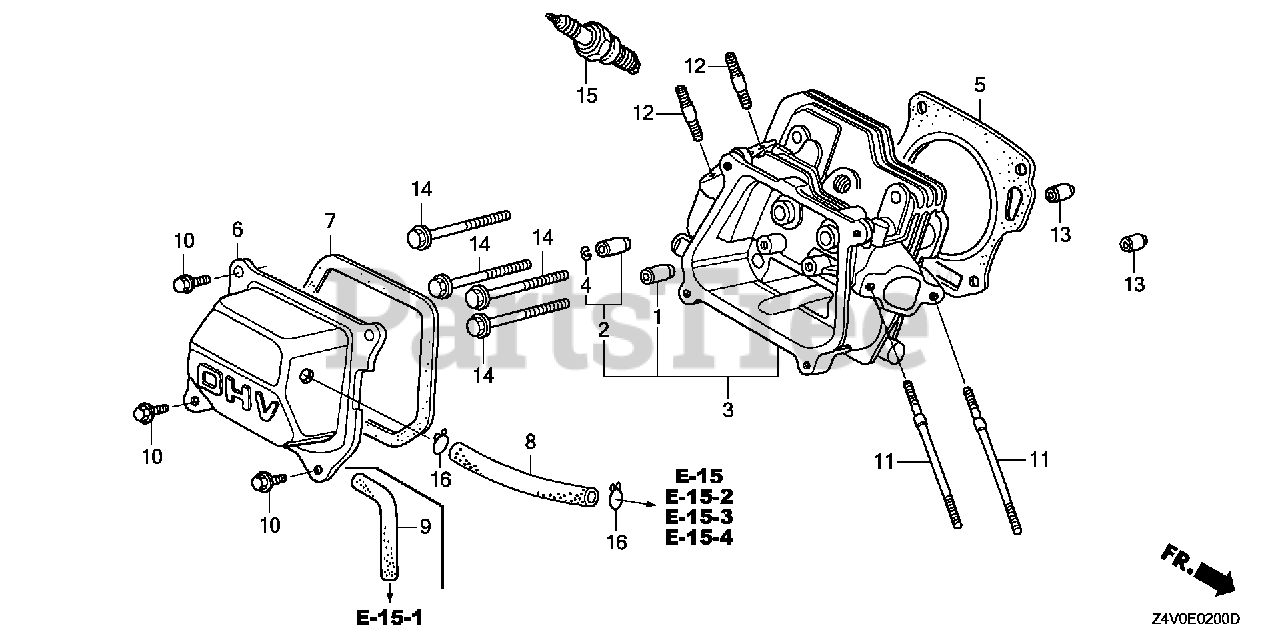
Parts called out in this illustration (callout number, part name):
1	GUIDE, VALVE (OVER SIZE) Use from Engine SN 6324986.
2	GUIDE, EX. VALVE (OS)
3	CYLINDER HEAD
4	CLIP, VALVE GUIDE Use from Engine SN 1231803.
5	GASKET, CYLINDER HEAD (NIPPON LEAKLESS)
6	COVER, HEAD
7	GASKET, CYLINDER HEAD COVER
7	GASKET, HEAD COVER
8	TUBE, BREATHER
10	BOLT, FLANGE (6X12) (CT200)
11	BOLT, STUD (6X109)
12	BOLT, STUD (8X32)
13	PIN A, DOWEL (10X16)
14	BOLT, FLANGE (8X60)
15	SPARK PLUG (BPR5ES) (NGK)
15	SPARK PLUG (W16EPR-U) (DENSO)
15	SPARK PLUG (BPR6ES) (NGK)
15	SPARK PLUG (W20EPR-U) (DENSO)
16	CLIP, TUBE (C12)
